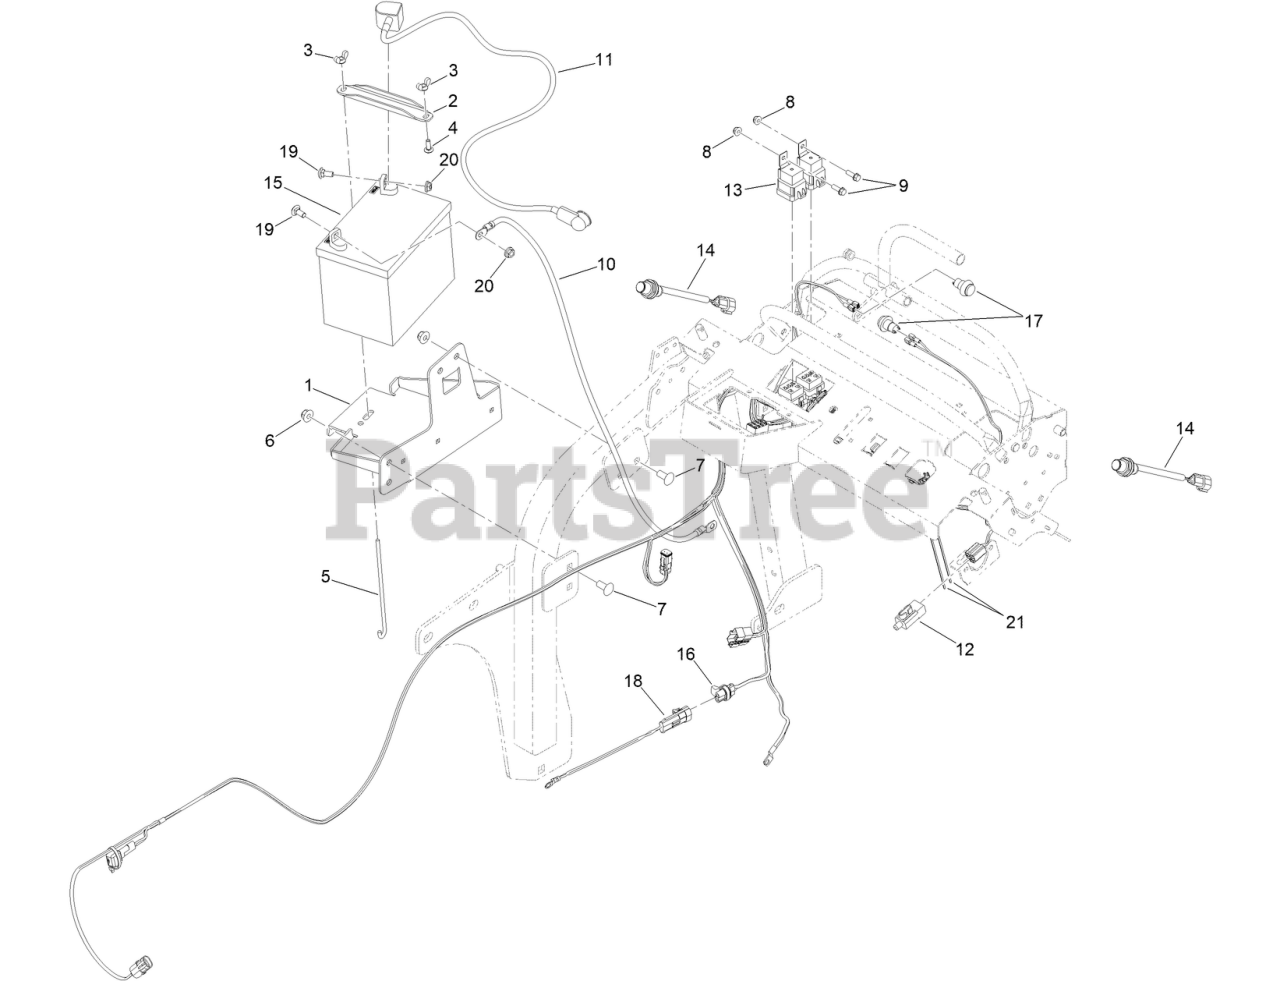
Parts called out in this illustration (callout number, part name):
1	BRACKET-MOUNT, BATTERY
2	BRACKET, TIE-DOWN
3	NUT-WING
4	BOLT-CARR
5	BOLT-HOLDDOWN
6	NUT-HF, NI
7	SCREW-CARR
9	SCREW-HWH
10	CABLE-BATTERY, NEGATIVE
11	CABLE-BATTERY, POSITIVE
12	SWITCH-REVERSE
13	RELAY-MINI
14	SENSOR-PROXIMITY, N.O.
15	Battery (340 CCA, Wet)
16	HARNESS-WIRE, MAIN
17	SWITCH-PB, MOMENTARY
18	HARNESS-WIRE, FUSIBLE LINK
19	BOLT-CARR
21	TIE-CABLE
